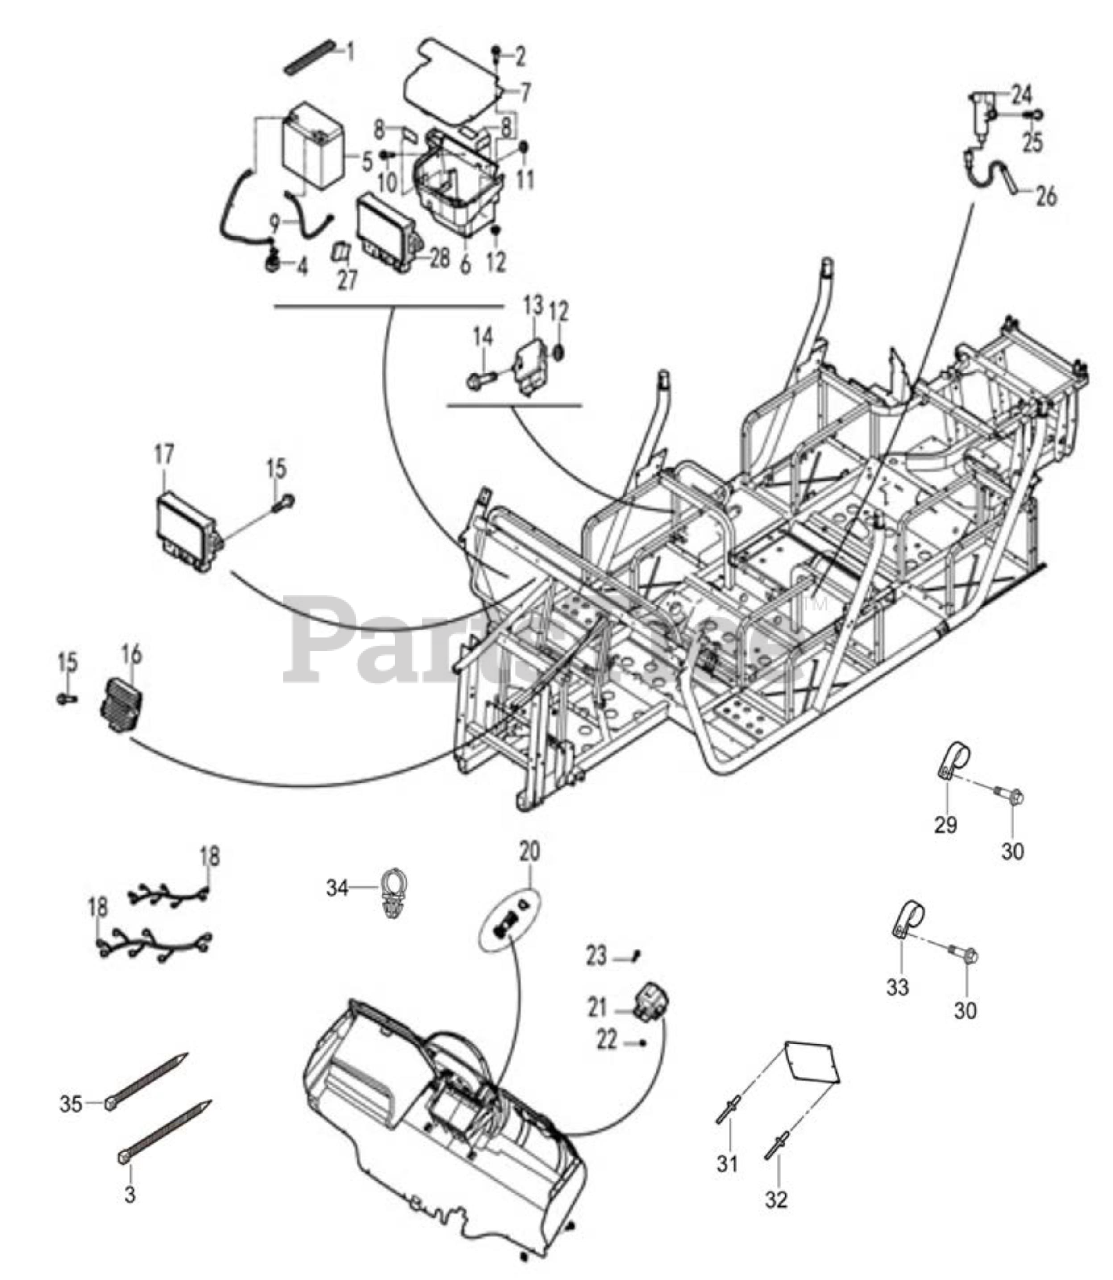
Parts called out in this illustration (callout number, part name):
1	Battery Dragline 152
2	Handle Bolt M6X20
3	Zip Tie =300
4	Starter Relay
5	Battery(30Ah)
6	Battery Case
7	Battery Cover
8	Buffering Foam Pad 50X35
9	Negative electrode cable,Power source
10	Hexagon Flange Bolt M6X16
11	Flat washer 6
12	Hexagon Flange Nut M6
13	ECU controller assy
14	Hexagon Flange BoltM6X20
15	Hexagon Flange BoltM6X20
16	Rectifier/Voltage regulator
17	Relay Assy
18	Main Cable Assy.
19	EFI Cable Assy(EFI Engine)
21	2/4 WD Switch
22	Hexagon Flange nut M5
23	Cross Large Plate Head Screw M5X16
24	Ignition Coil
25	Hexagon Flange Bolt M6X40
26	connector wire for ignition coil
28	Main Relay Assy
29	Water Pipe attach clamp ?
30	Flange Bolt M6X16
31	Self-plugging rivet 3.2X11
32	Self-plugging rivet 3.2X7
33	Oil pipe attach clamp I
34	Pin Clamp II
35	Zip Tie =200
